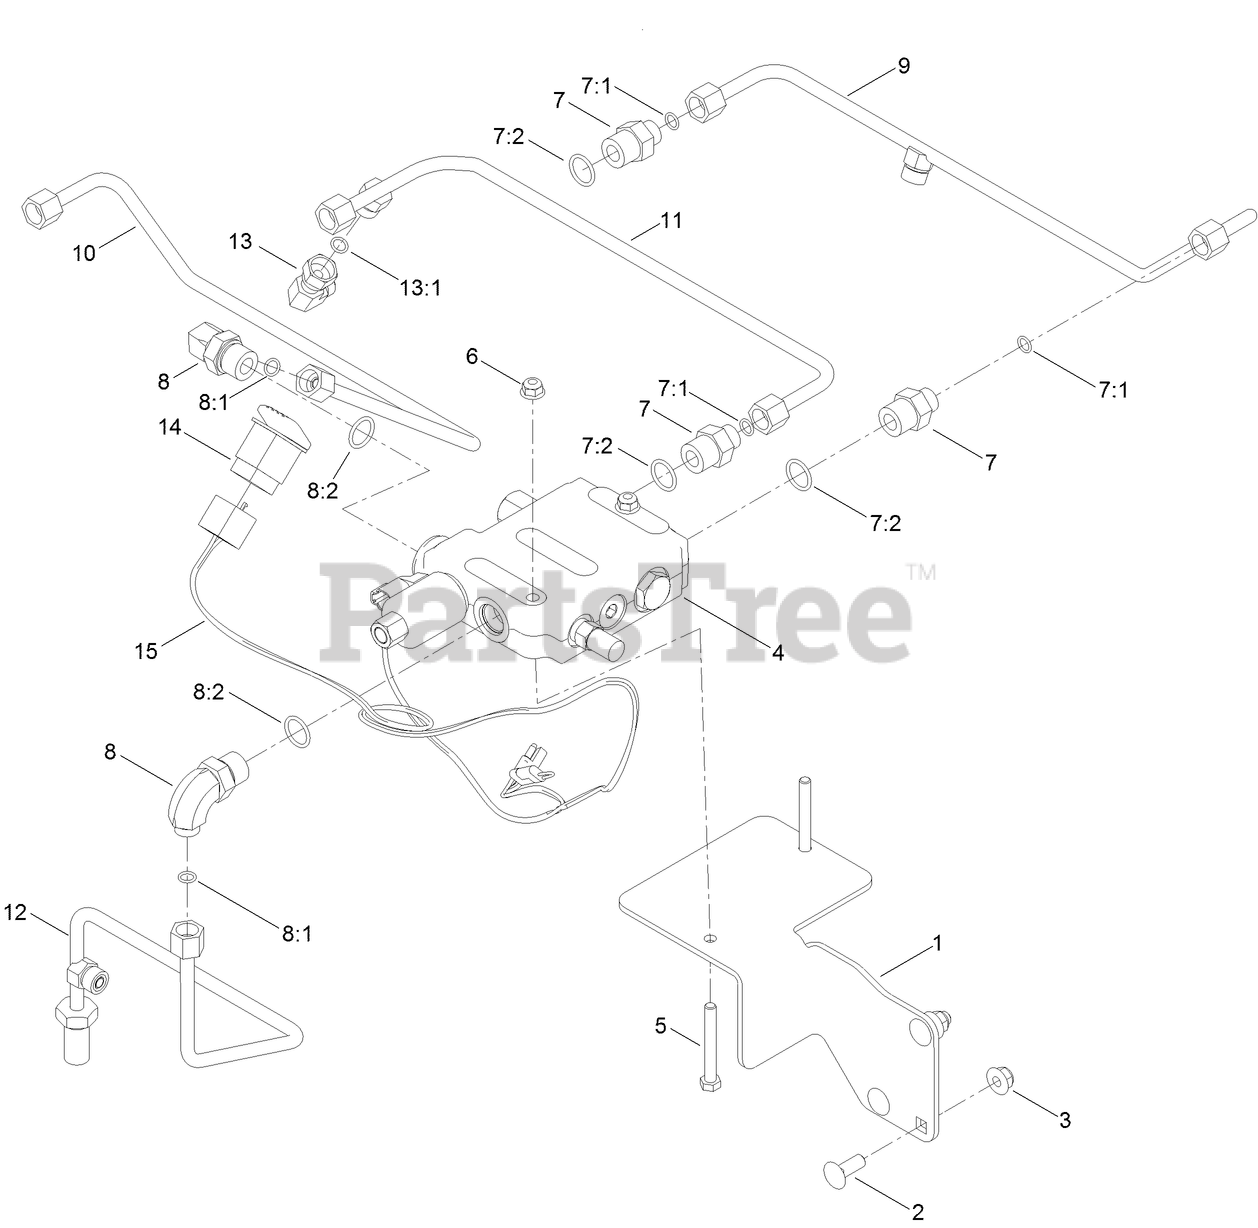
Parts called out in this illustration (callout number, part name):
1	BRACKET-MOUNT, LEVELING VALVE
2	SCREW-CARR
3	NUT-HF, NI
4	VALVE-LEVELING,
5	SCREW-HH
6	NUT-HF, NI
7	FITTING-STR
7:1	O-RING
7:2	O-RING
8	FITTING-ELBOW 90
8:1	O-RING
8:2	O-RING
9	HYD TUBE ASM
10	HYD TUBE ASM
11	HYD TUBE ASM
12	HYD TUBE ASM
13	FITTING-HYD, 90 DEG
13:1	O-RING
14	SWITCH
15	HARNESS-WIRE,
